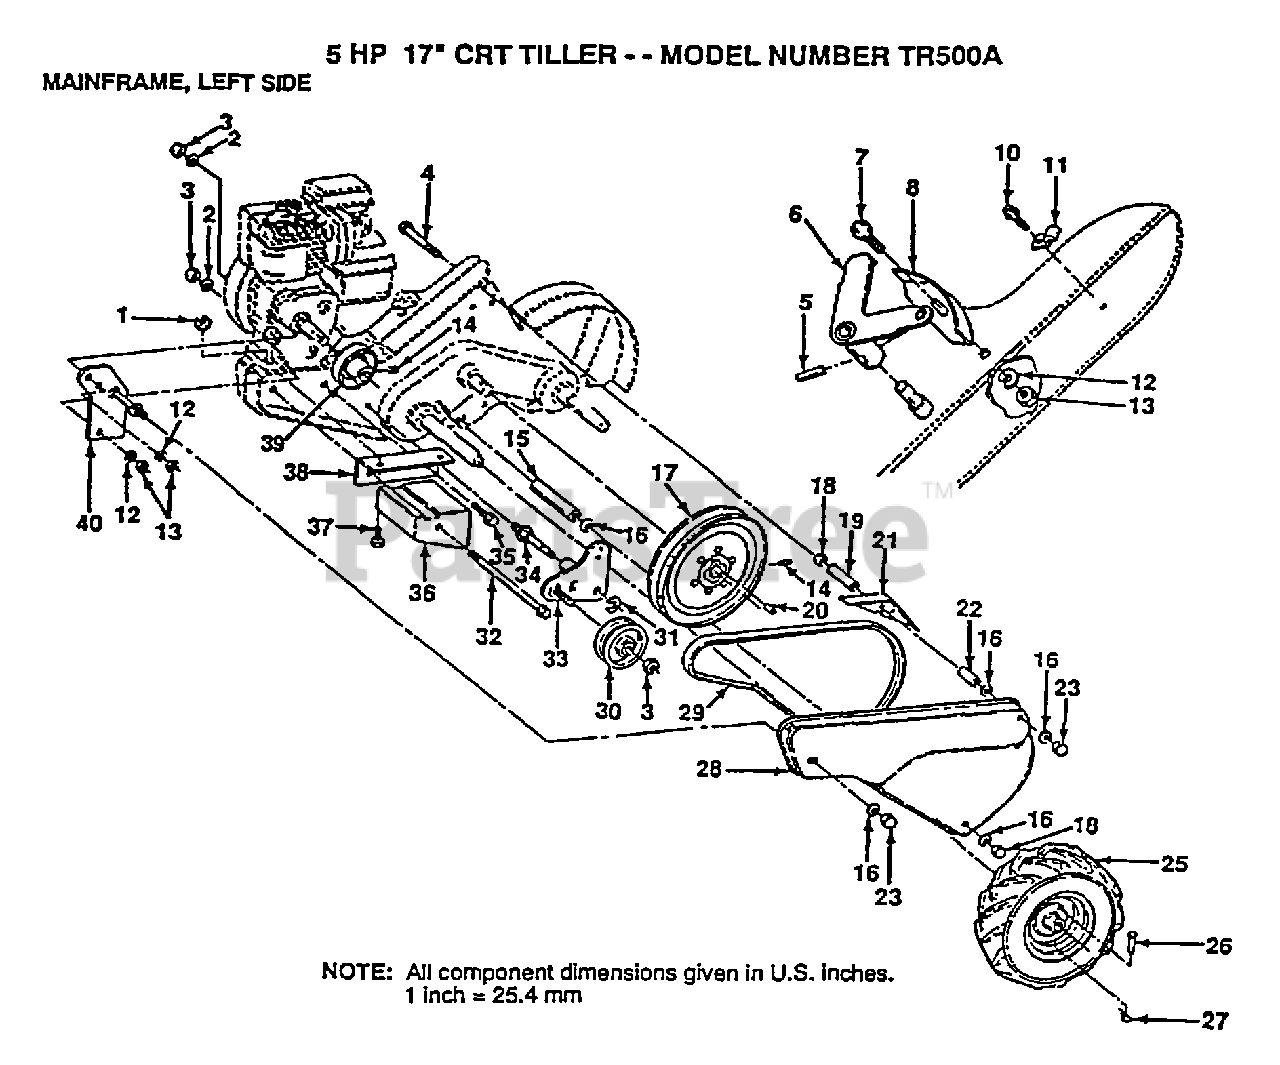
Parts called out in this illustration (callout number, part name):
2	LOCKWASHER
3	NUT.HEX.3/8-16UNC
4	BOLT-HEX TI
6	LEVER ASM CRT
7	BOLT
8	PANEL TI
11	CONDIUT CLIP T
12	LOCKWASHER
14	SET SCREW
15	SPACER
16	WASHER
17	"SHEAVE 10"" CRT"
18	NUT.HEX.5/16-18
19	SPACER CRT
20	KEY T
21	GUARD CRT
22	SPACER CRT
23	NUT TI
25	TIRE.CHV.13X5.0-6
26	RIVET.DRILL.1.75
27	RETAINER M
30	PULLEY-IDLER TI
31	KLIP RING
32	BOLT CRT
34	SHIFT ARM CRT
35	BOLT
36	COUNTERWEIGHT CRT
37	BOLT.HEX.5/16-1.5
38	BRACKET LH CRT
40	BRACKET ASSY CRT
